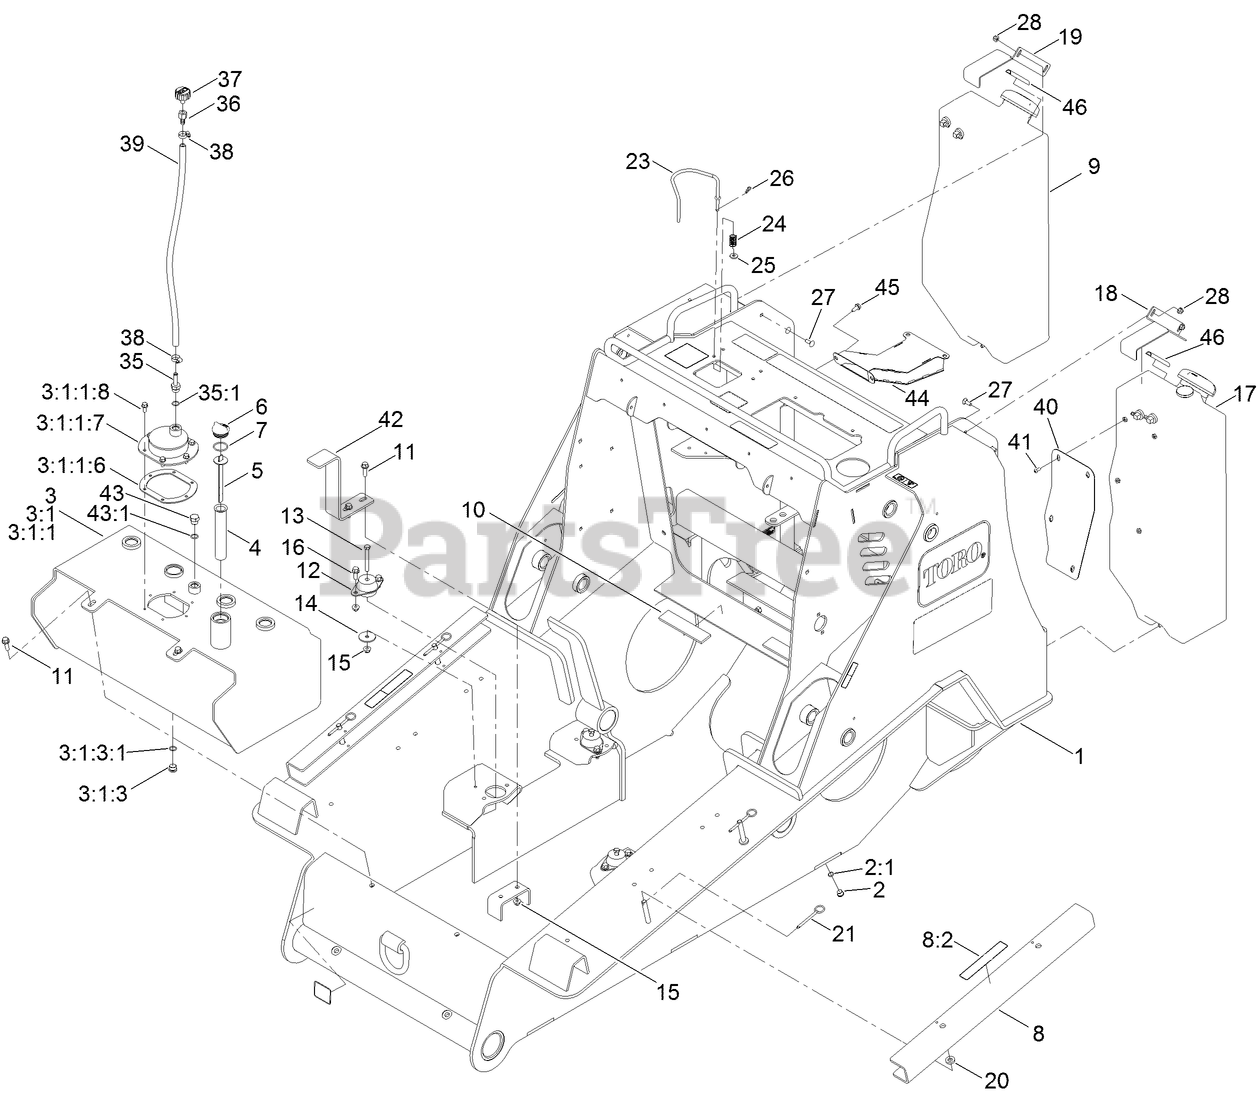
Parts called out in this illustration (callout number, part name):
1	FRAME ASM
2	PLUG-HEX, HOLLOW
2:1	O-RING
3	HYD TANK ASM
3:1	TANK-HYD
3:1:1	TANK-HYD, TOP
3:1:1:6	GASKET-COVER, ACCESS
3:1:1:7	COVER-ACCESS
3:1:1:8	SCREW-HHF
3:1:3	PLUG-HEX
3:1:3:1	O-RING
4	FILTER-SCREEN
5	DIPSTICK
6	PLUG-PLASTIC
7	O-RING
8	ARM-LOCKING
8:2	DECAL-DANGER
9	RH FUEL TANK ASM
10	PAD-RUBBER
11	SCREW-HHF
12	MOUNT-ENGINE
13	SCREW-HH
14	WASHER-REBOUND
15	NUT-HF, NI
16	SCREW-HHF
17	LH FUEL TANK ASM
18	BRACKET-TANK, LH
19	BRACKET-TANK, RH
20	WASHER-NEOPRENE
21	PIN-RING
23	ROD-INTERLOCK
24	SPRING-CONTROL
25	WASHER-FLAT
27	SCREW-CARR
28	NUT-HF, NI
35	FITTING-STR
35:1	O-RING
36	FITTING-FEMALE, BARBED
37	BREATHER
38	CLAMP-HOSE
39	HOSE-FUEL
40	PLATE-GUARD, TANK
41	SCREW-HSBH
42	STRAP-HOLD DOWN
43	PLUG-HYD, HH
43:1	O-RING
44	INTAKE CHUTE ASM,
45	SCREW-HWH
46	SEAL-BULB
